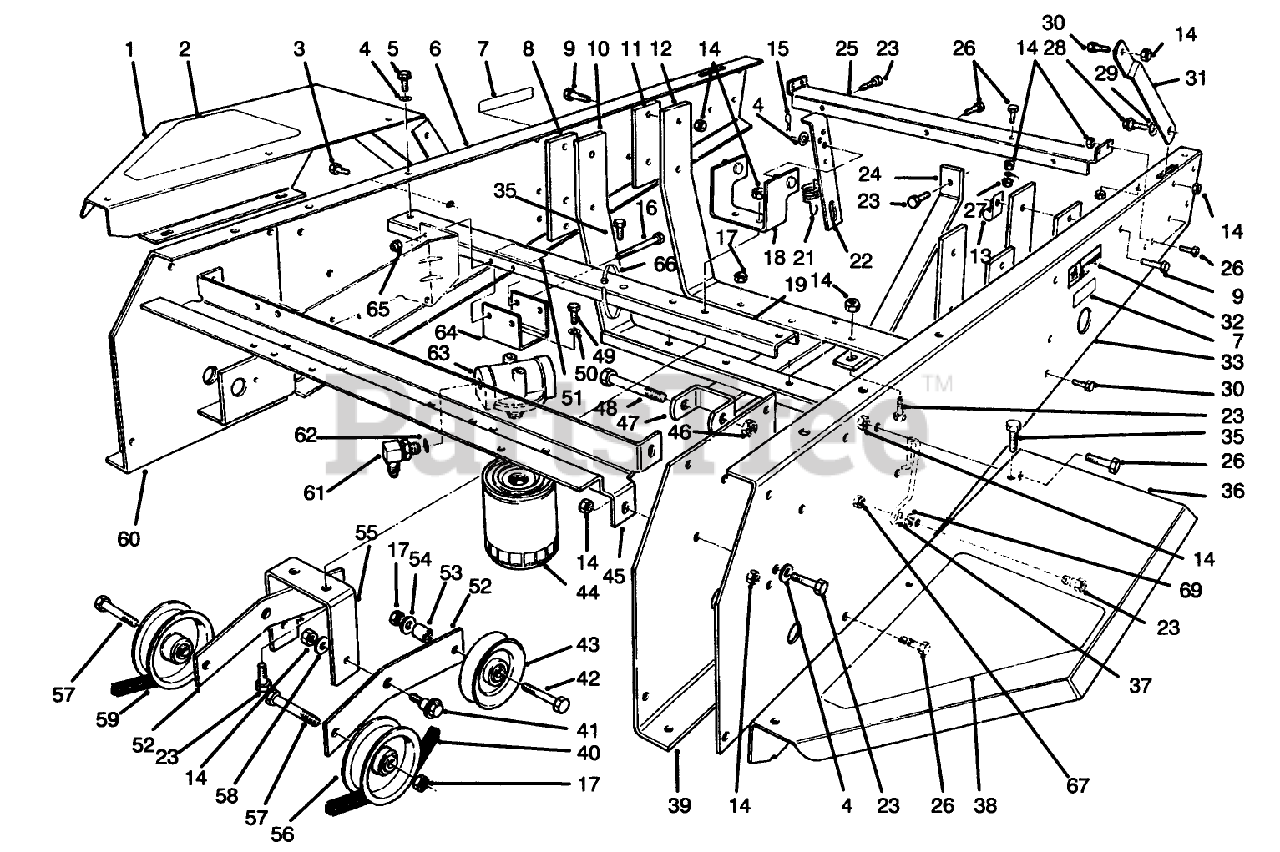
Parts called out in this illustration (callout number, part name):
2	RH FENDER PAD
3	SCREW-HHF
4	WASHER-PLAIN
5	SCREW-THD ROLL, HWH
7	DECAL-WARNING
8	FRONT ENG PLATE
9	SCREW-HH
11	REAR ENG PLATE
14	NUT-LOCK, NI
15	PIN-COTTER
16	SCREW-HH
17	NUT-LOCK, NI
19	MIDDLE CHANNEL WA *B
20	SCREW-HH
21	IDLER SPRING
23	SCREW-HH
26	SCREW-HH
27	NUT-KEPS
28	SCREW-SHOULDER
29	WASHER-SPRING
30	SCREW-HH
32	DECAL-HOT
35	SCREW-HHFTF
37	BELT GUIDE
38	LH FENDER PAD
40	V-BELT, JACKSHAFT
41	SCREW-SHOULDER
42	SCREW-HH
43	PULLEY
44	FILTER-OIL, TRANSMISSION
46	NUT-LOCK
48	SCREW-HH
49	SCREW-HH
50	WASHER-LOCK
51	DECAL-OIL
53	SPACER-WEIGHT
54	WASHER-FLAT
56	PULLEY
57	SCREW-HH
58	WASHER
59	V-BELT, TRACTION
62	O-RING
63	FILTER HD ASM
64	BRACKET - FILTER HEAD
65	NUT-LOCK, NI
66	TIE-CABLE
67	NUT-HF
69	WASHER-LOCK
